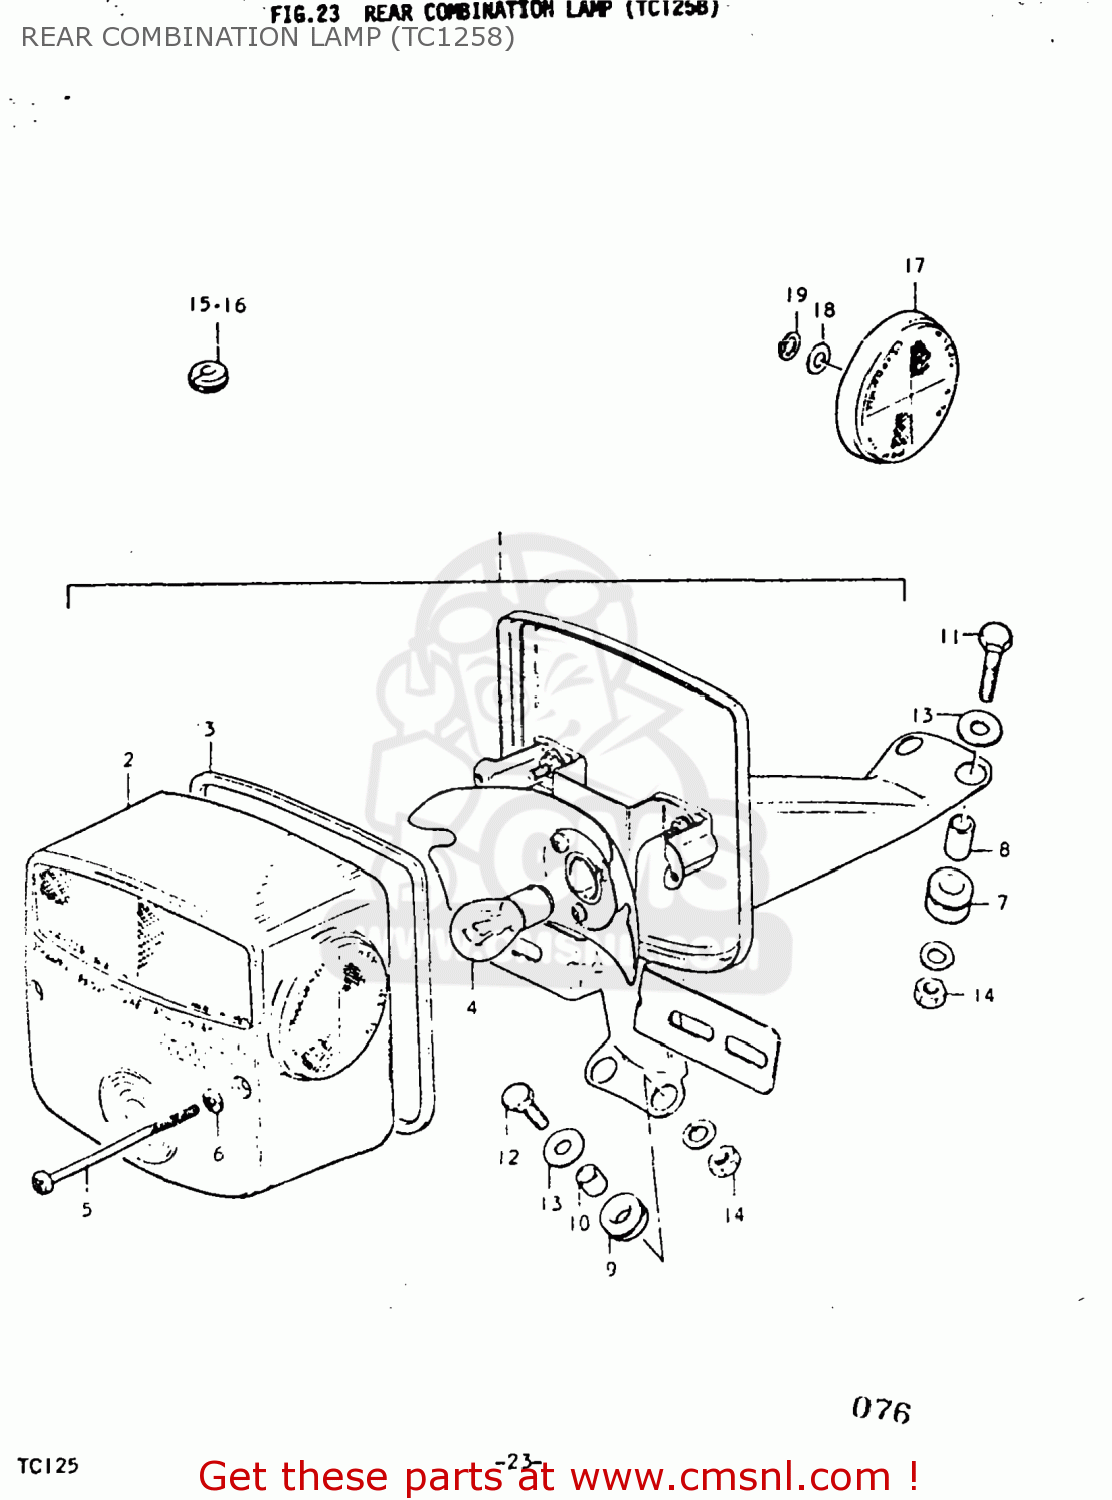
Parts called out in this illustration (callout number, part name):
1	LAMP ASSEMBLY,REAR COMBINATION
2	LENS,REAR COMBINATION LAMP
3	GASKET (NAS)
4	BULB(6V32/3CP,STANLEY)
5	SCREW
6	GASKET (NAS)
7	CUSHION
8	SPACER,REAR COMBINATION LAMP
9	CUSHION
10	SPACER,REAR COMBINATION LAMP
11	BOLT
12	BOLT
13	WASHER (6.5X20X1.2)
14	NUT
15	GROMMET
16	GROMMET
17	REFLEX REFLECTOR,FR
18	WASHER
19	LOCK WASHER
